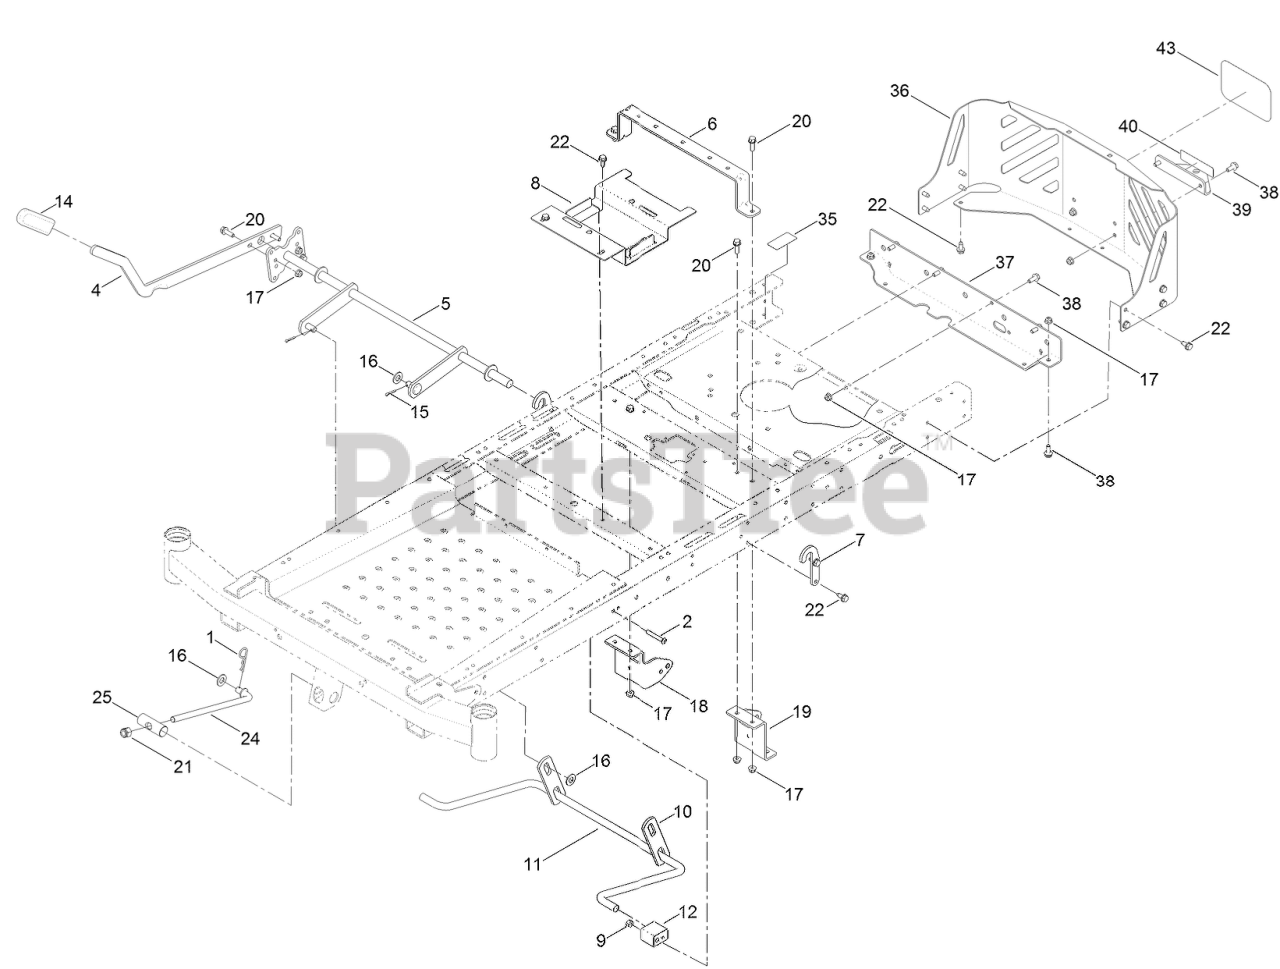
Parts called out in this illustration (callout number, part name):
1	PIN-COTTER
2	SCREW-HSBH
4	LEVER-LIFT
5	LIFT-DECK, NARROW
6	BRACE-SEAT, REAR (NARROW)
7	BRACKET-LIFT
8	BRACKET-BATTERY
9	NUT-LOCK, NI
10	LINK-LIFT
11	ARM-LIFT, REAR
12	BLOCK-PIVOT
14	GRIP-LEVER
15	PIN-COTTER
16	WASHER-FLAT
17	NUT-HF, NI
18	MOUNT-HYDRO, FRONT (RH)
19	MOUNT-HYDRO, FRONT (LH)
20	SCREW-HHF
21	NUT-HEX
22	SCREW-HWHTF
24	ROD-MOUNT, DECK
25	PIN-PIVOT
35	DECAL-BYPASS
36	GUARD-ENGINE, NARROW
37	CROSSMEMBER-REAR, NARROW
38	SCREW-HHF
39	BRACKET-HITCH
43	DECAL
